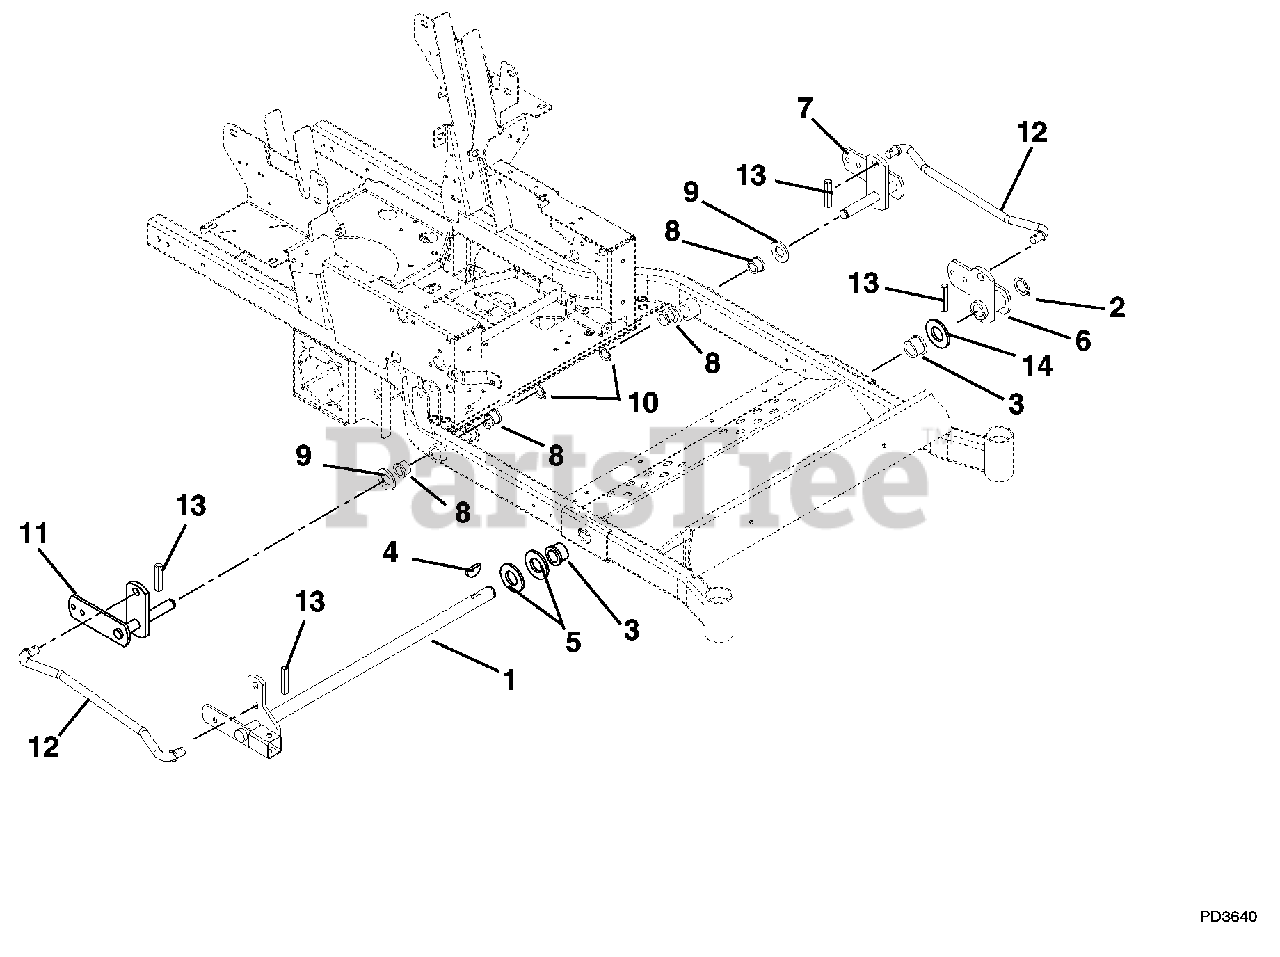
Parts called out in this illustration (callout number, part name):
1	Weldment, Lift Arm
2	Ring, Retaining External 1.00 x .078
3	Bushing, Flange Nylon 1.020 x 1.385 x .75 x 1.75
4	Key, Woodruff .25 x 1.00
5	Washer, Flat Steel 1.063 x 2.00 x .134
6	Lift Arm - Front
7	Lift Arm Shaft - Left Hand
8	Bushing, Flange Nylon .762 x 1.0 x .580 x 1.48
9	Washer, Hardened Steel .758 x 1.23 x .031
10	Ring, Retaining External .689 x .077
11	Lift Arm Shaft - Right Hand
12	Rod, Lift Assist
13	Pin, Roll .25 x 1.25
14	Washer, Hardened Thrust 1.00 x 1.55 x .03
